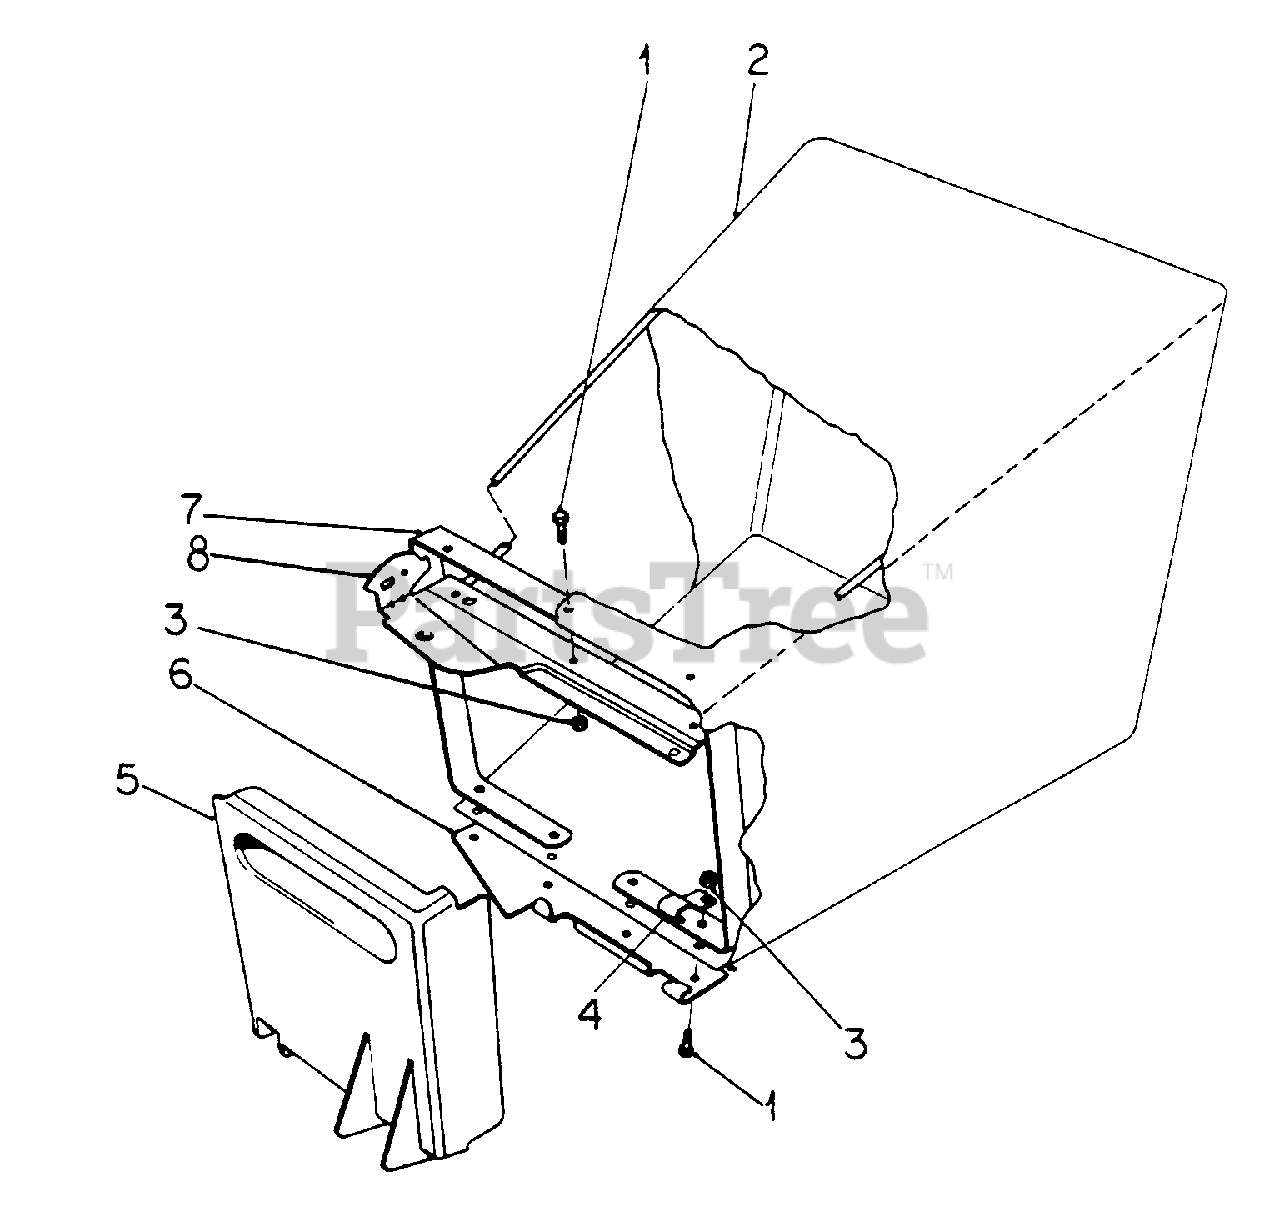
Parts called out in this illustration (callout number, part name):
1	SCREW, NO. 10 X 1/2 ZNP H/HD MACH
3	NUT, NO. 10 CAD P/T LOCK TYPE 5
4	BRACKET, SUPPORT
6	BRACKET, DOOR
7	SUPPORT, BAG
